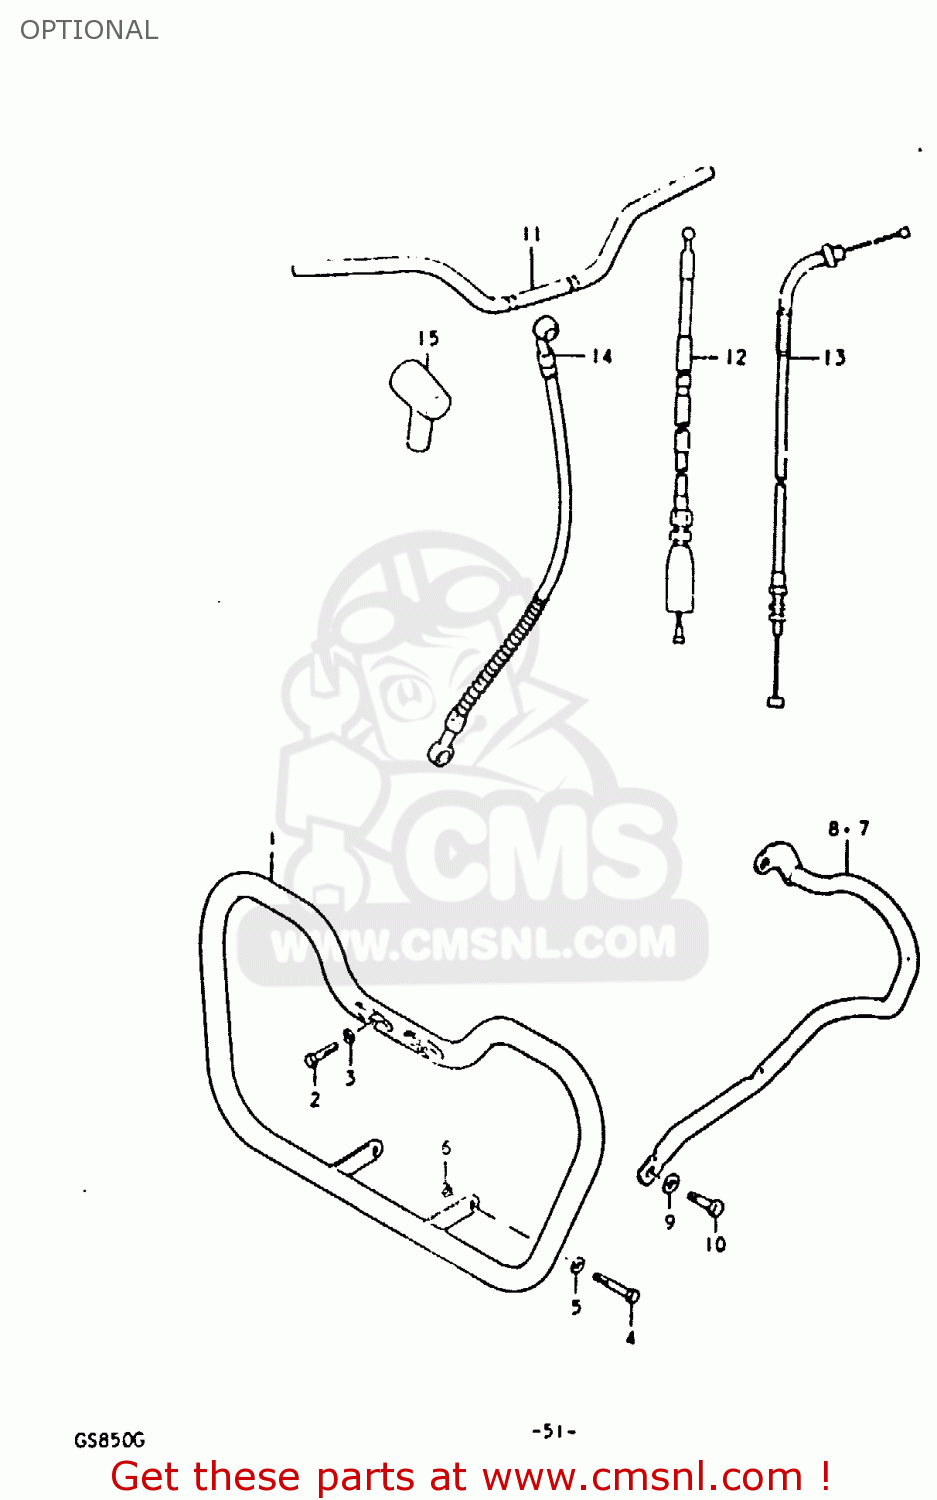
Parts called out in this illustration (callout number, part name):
1	BUMPER FRONT
2	BOLT 8X45
3	LOCK WASHER
4	BOLT
5	WASHER
6	NUT
7	BUMPER, RH REAR
8	BUMPER, LH REAR
9	WASHER (10.1X21X2.3)
10	BOLT(10X45)
11	HANDLEBAR
12	CABLE ASSY,CLU
13	CABLE ASSY,THROTTLE
14	HOSE,FRONT BRAKE
15	BOOT
